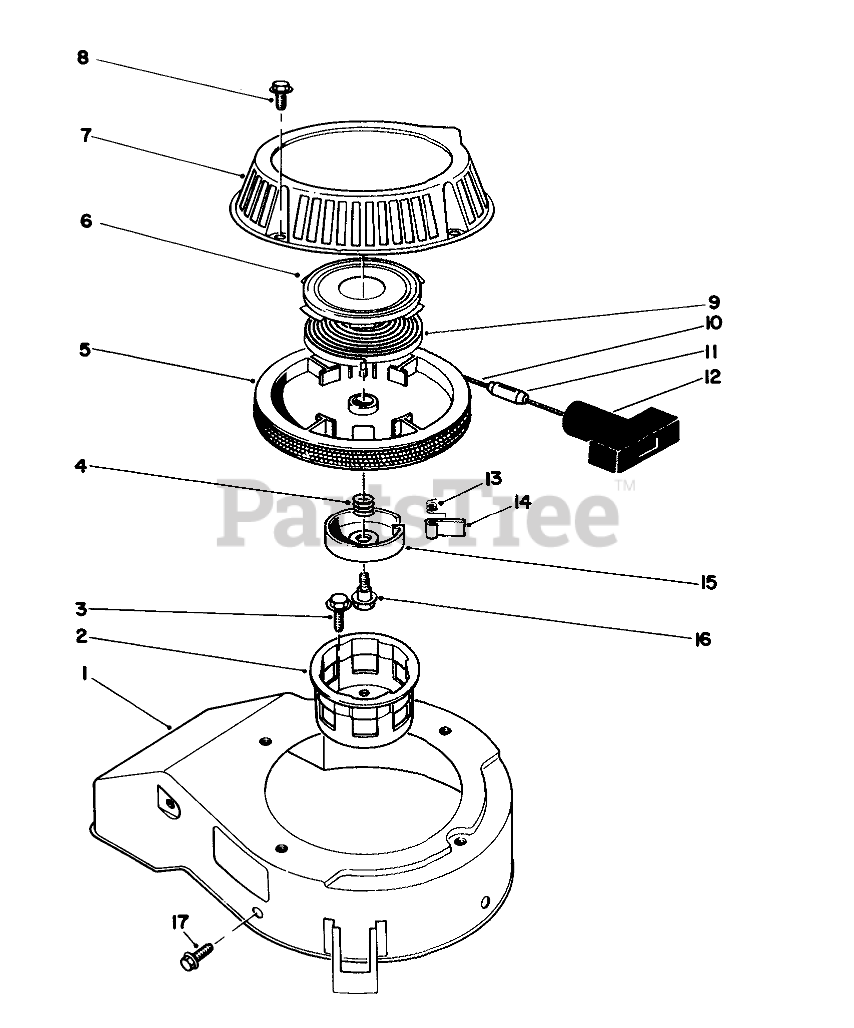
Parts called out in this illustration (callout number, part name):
1	COVER
2	CUP - STARTER
4	SPRING
6	Retainer-Recoil Spring
8	SCREW-HHF
9	Spring-Recoil
10	ROPE-STARTER
12	HANDLE-RECOIL
13	SPRING
15	RETAINER
